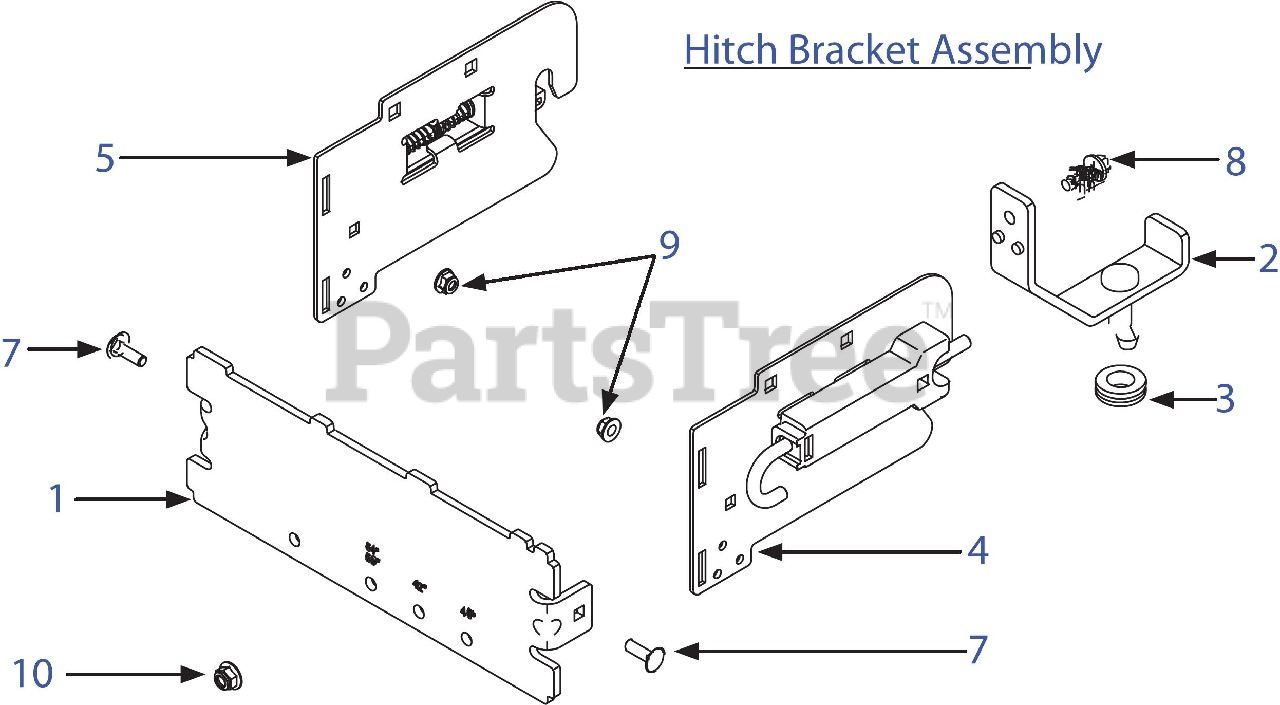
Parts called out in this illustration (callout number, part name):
2	Bracket Support Assembly
3	Rubber Grommet
4	RH Bracket Assembly
5	LH Bracket Assembly
6	Hitch Hardware Pack
7	Carriage Screw: 5/16-18: 1.0
8	Hex Screw: 3/8-16: 1.0
9	Nylon Lock Nut: 5/16-18
10	Flange Lock Nut:3/8-16
